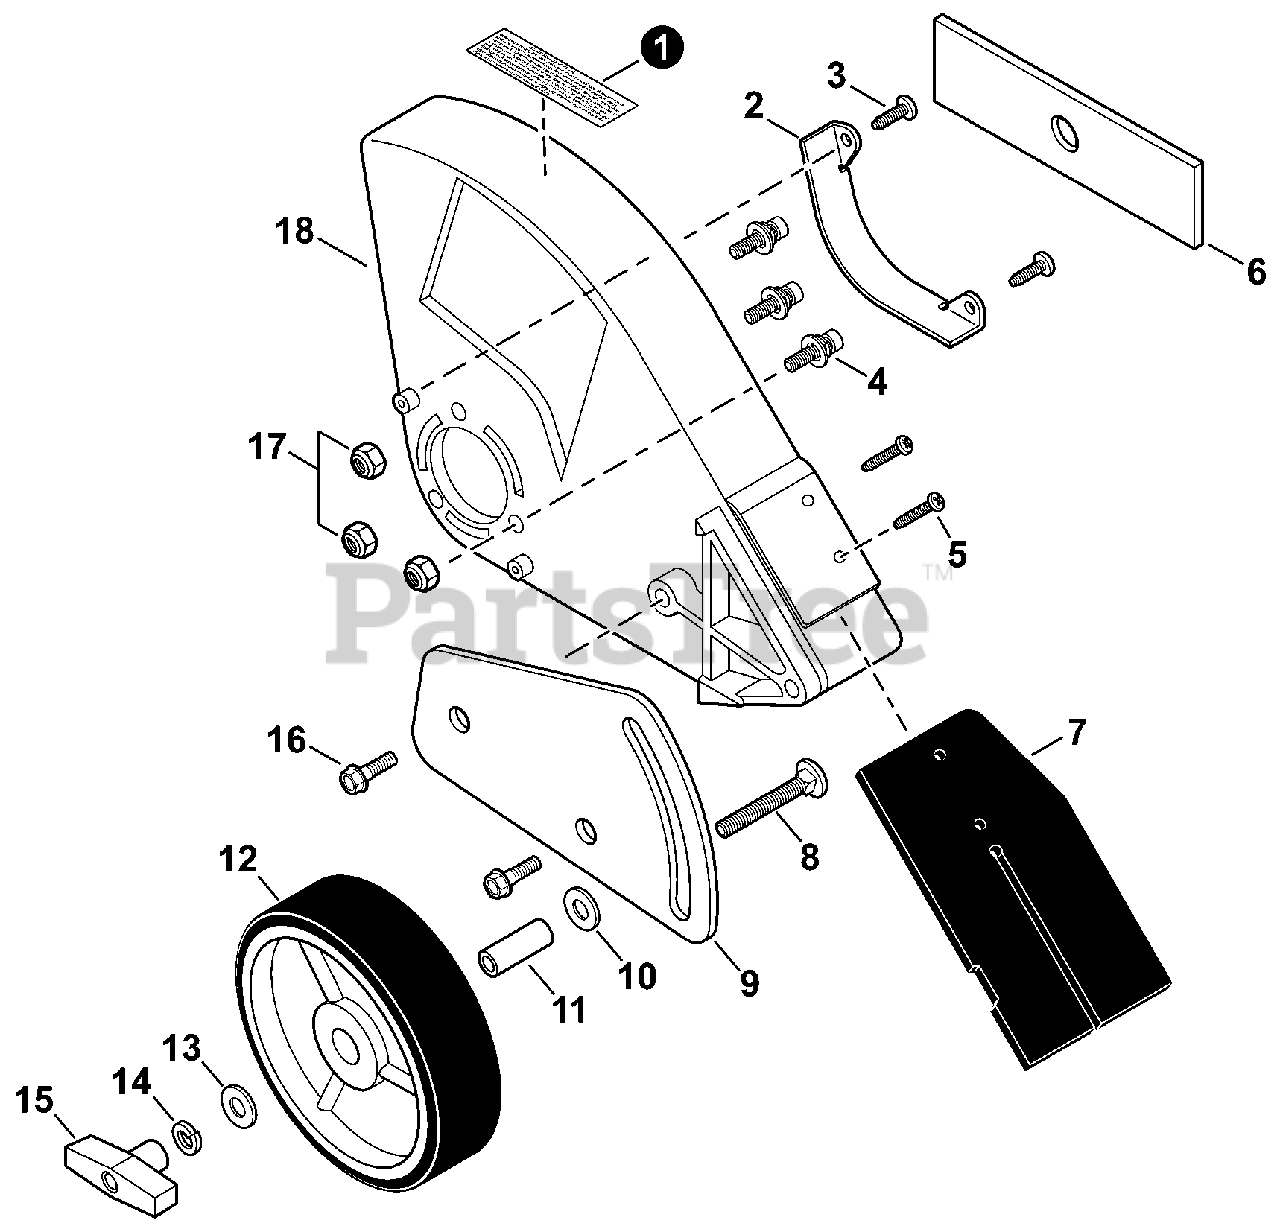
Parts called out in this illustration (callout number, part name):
1	LABEL, CAUTION
2	GUARD, SHIELD
4	BOLT 5×22
6	BLADE - 2 PK
7	FLAP, DEBRIS
8	BOLT 5/16×18×2 1/2
9	BRACKET, WHEEL
10	WASHER 10
11	COLLAR 12
12	WHEEL
13	WASHER 8
14	WASHER, SPRING 8
15	KNOB, FASTENER
17	NUT, LOCK M5
18	SHIELD, DEBRIS
